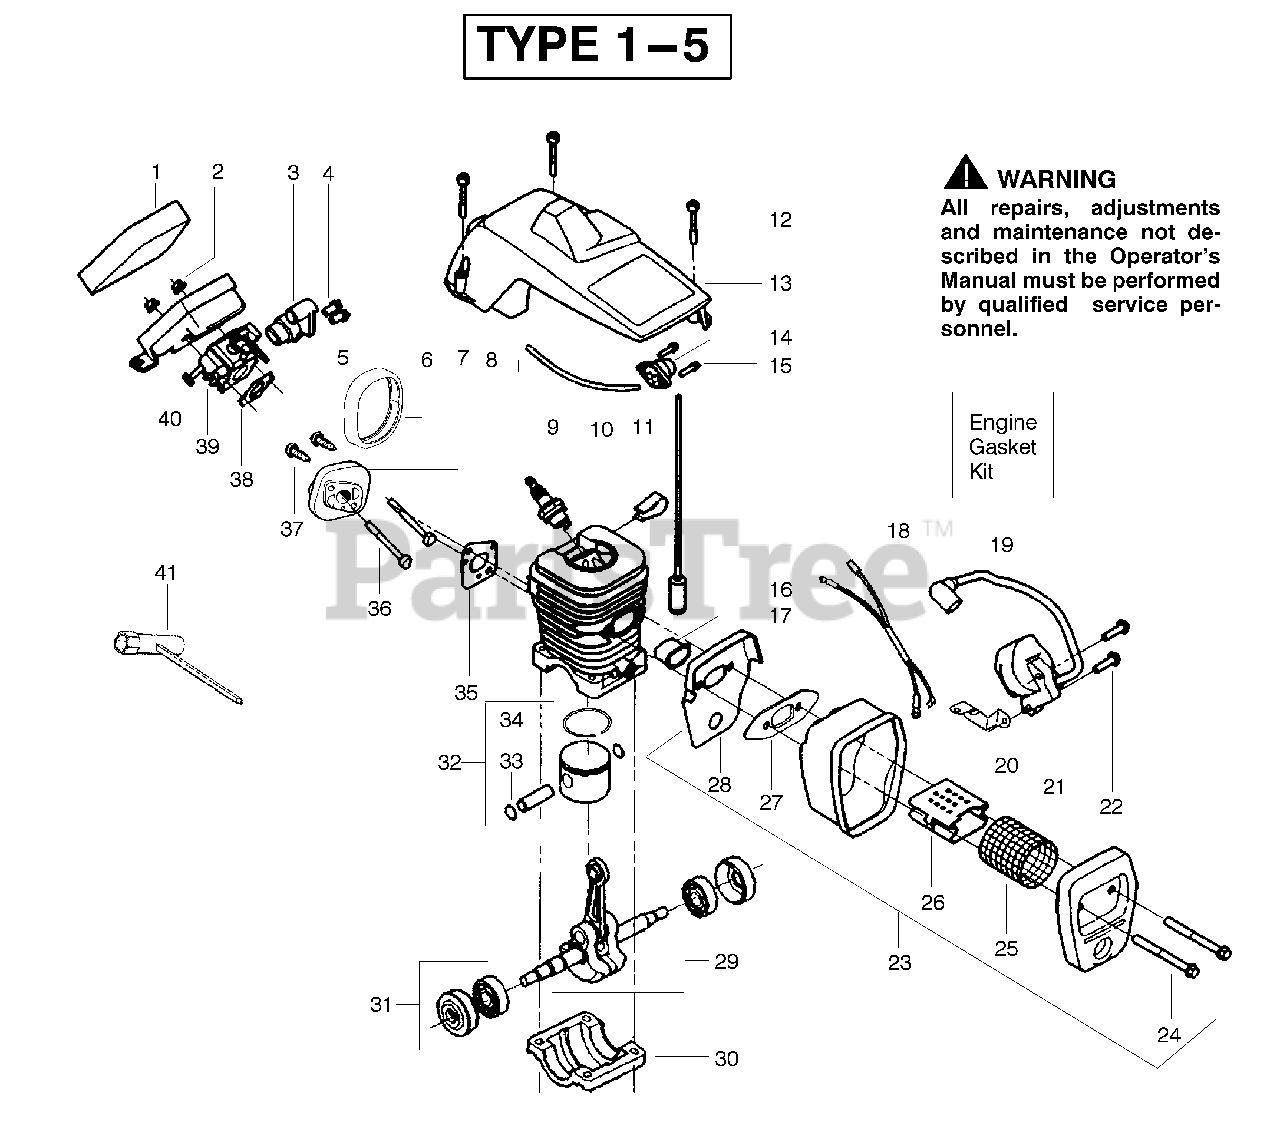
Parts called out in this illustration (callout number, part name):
1	Foam- Air Filter
3	Grommet-Carb Adjust
4	Limiter Cap-High
5	Limiter Cap-Low
6	Seal-Carb Adapter
7	Carb. Adapter
8	Kit-Fuel Line
9	Spark Plug
10	Kit-Cylinder
11	Clip-High Tension Lead
13	Shield-Cylinder
14	Assy- Air Purge
16	Assy-Fuel Pick-up
17	Insulator-Heat
18	Assy. - Wire Harness
19	Kit-Engine Gasket
20	Strap - Ground
21	Module- Ignition
23	Assy-Muffler
25	Screen-Spark
26	Diffuser-Muffler
27	Gasket-Muffler
28	Backplate-Muffler
29	Assy. - Crankshaft
30	Cap-Crankcase
31	Assy.-Seal & Bearing
32	Kit-Piston
33	Retainer-Piston Pin
34	Ring - Piston
35	Gasket-Carb. Adap.
38	Gasket - Carb.
39	Kit-Carburetor
40	Housing- Air Filter
41	Wrench - Bar
